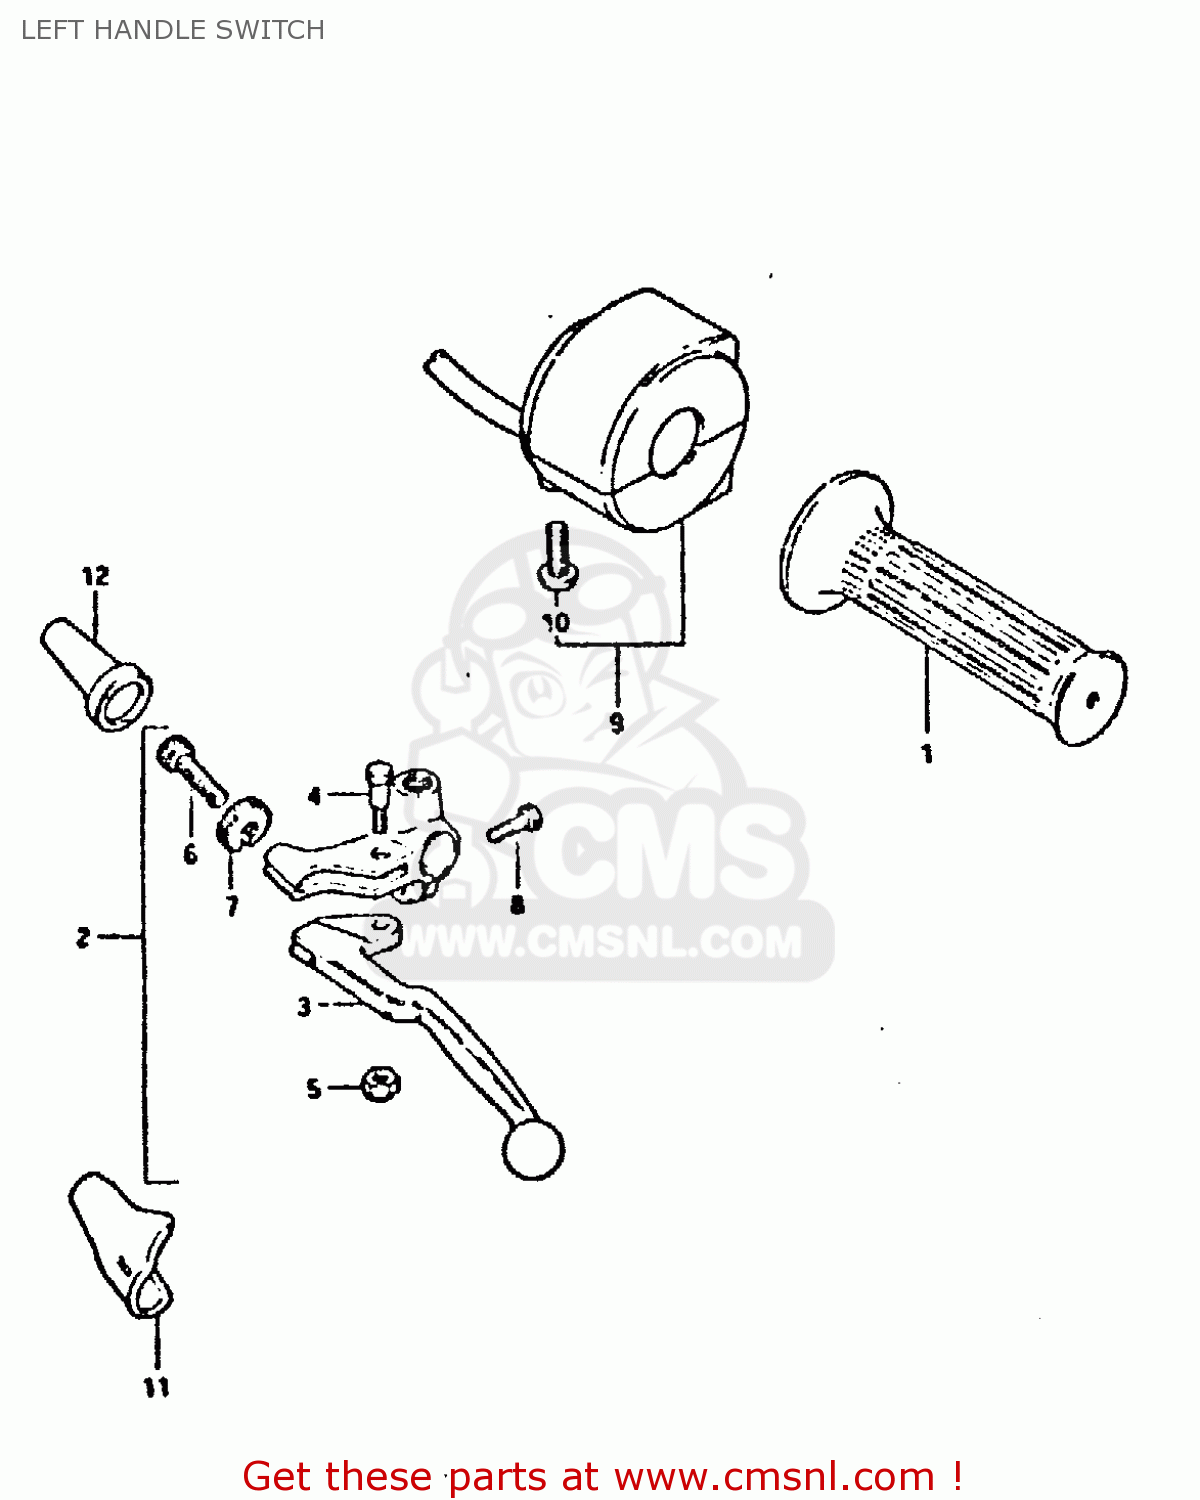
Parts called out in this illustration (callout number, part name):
1	GRIP,LEFT
2	LEVER ASSY, CLUTCH
3	LEVER,CLUTCH
4	BOLT,LEVER
5	NUT 6MM
6	ADJUSTER,CABLE
7	NUT,CABLE ADJUSTER
8	BOLT
9	SWITCH ASSY, HANDLE LH
10	SCREW
11	COVER,CLUTCH LEVER
12	BOOT,CLUTCH CABLE
